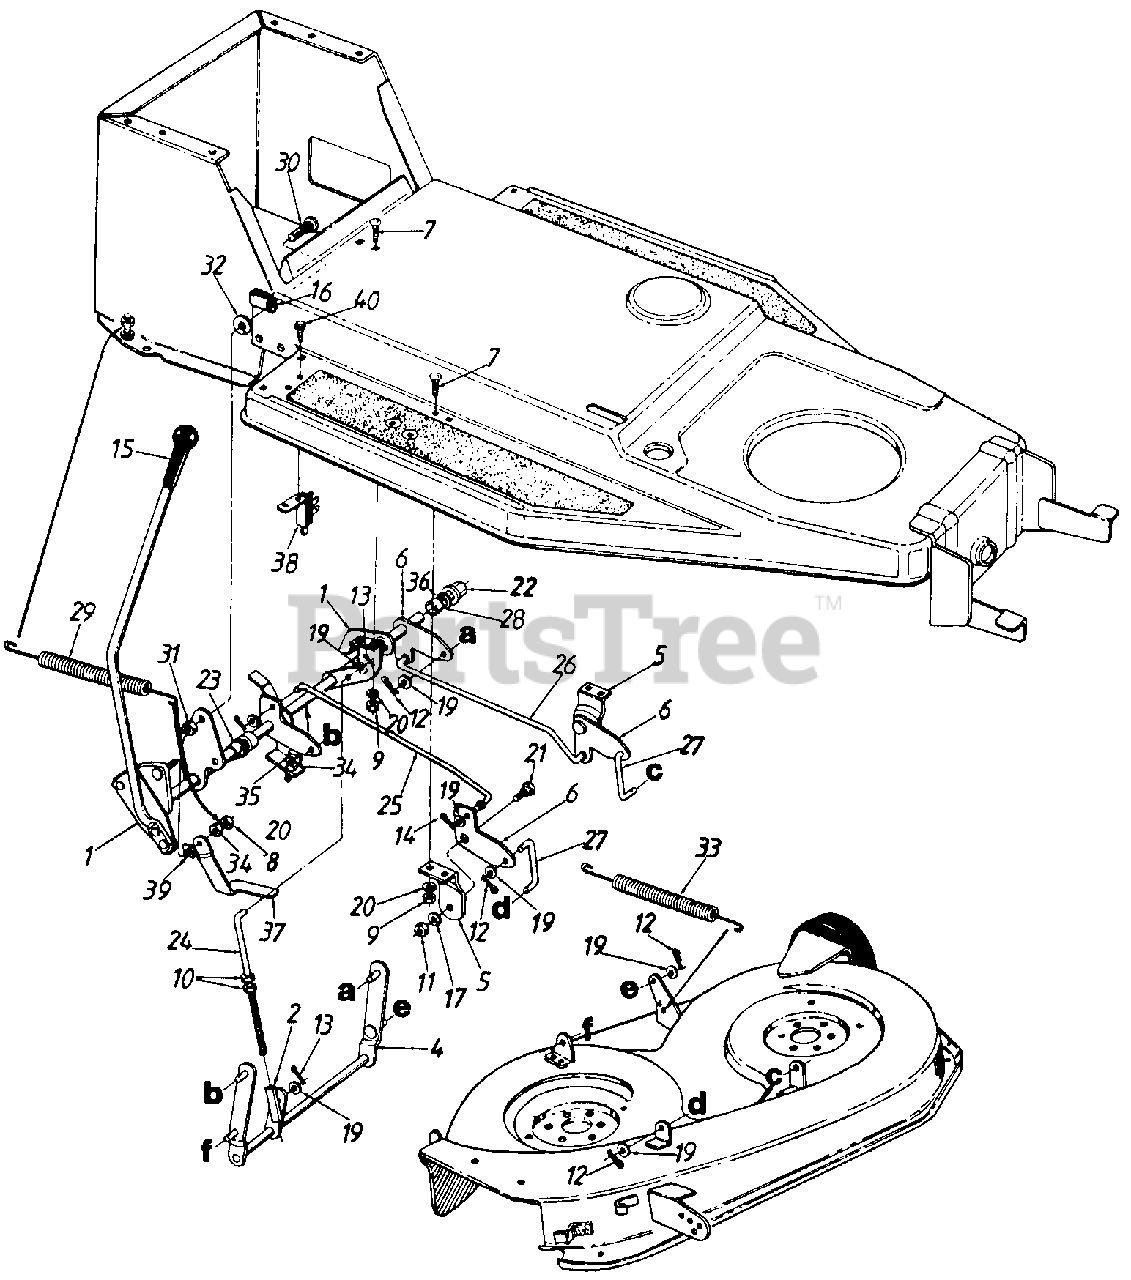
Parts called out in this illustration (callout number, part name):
1	Lift Shaft Ass'y.
2	Pivot Sleeve Ass'y.
6	Deck Lift Float Brkt.
7	Carr. Bolt 1/4-20 x .62" Lg.
8	Hex L-Nut 5/16-18 Thd.
9	Hex Nut 1/4-20 Thd.
10	Hex L-Nut 3/8-24 Thd.
11	Hex Nut 3/8-16 Thd.
12	Intern. Cot-Pin 5/16" Dia.
13	Cot-Pin 1/8" Dia.
14	Cot-Pin 3/32" Dia.
16	Clamp
17	L-Wash. 3/8" I.D.
19	Fl-Wash. .406" I.D. x .75" O.D.
20	L-Wash. 1/4" I.D.
21	Shld. Bolt .625 Dia. x .170" Lg.
22	Hex Flange Brg.
23	Nyliner Flanged Brg.
24	J-Bolt 3/8-16 x 5.25" Lg.
25	Connecting Rod R.H.
26	Connecting Rod L.H.
27	Lift Link
28	Spacer
29	Spring 8.65" Lg.
30	Ribbed Neck Bolt 3/8-24 x .80" Lg.
31	Hex Nut 3/8-24 Thd.
32	L-Wash. 3/8" I.D. H.D.
33	Deck Spring 10.33" Lg.
34	Hex Nut 5/16-18 Thd.
35	Hex Wash. Hd. Tap Scr. 5/16-18 x 1.0" Lg.
36	Spr. Wash. .625" I.D.
39	L-Wash. 5/16" I.D.
40	Truss Mach. B-Tap Scr. #10 x .5" Lg.
